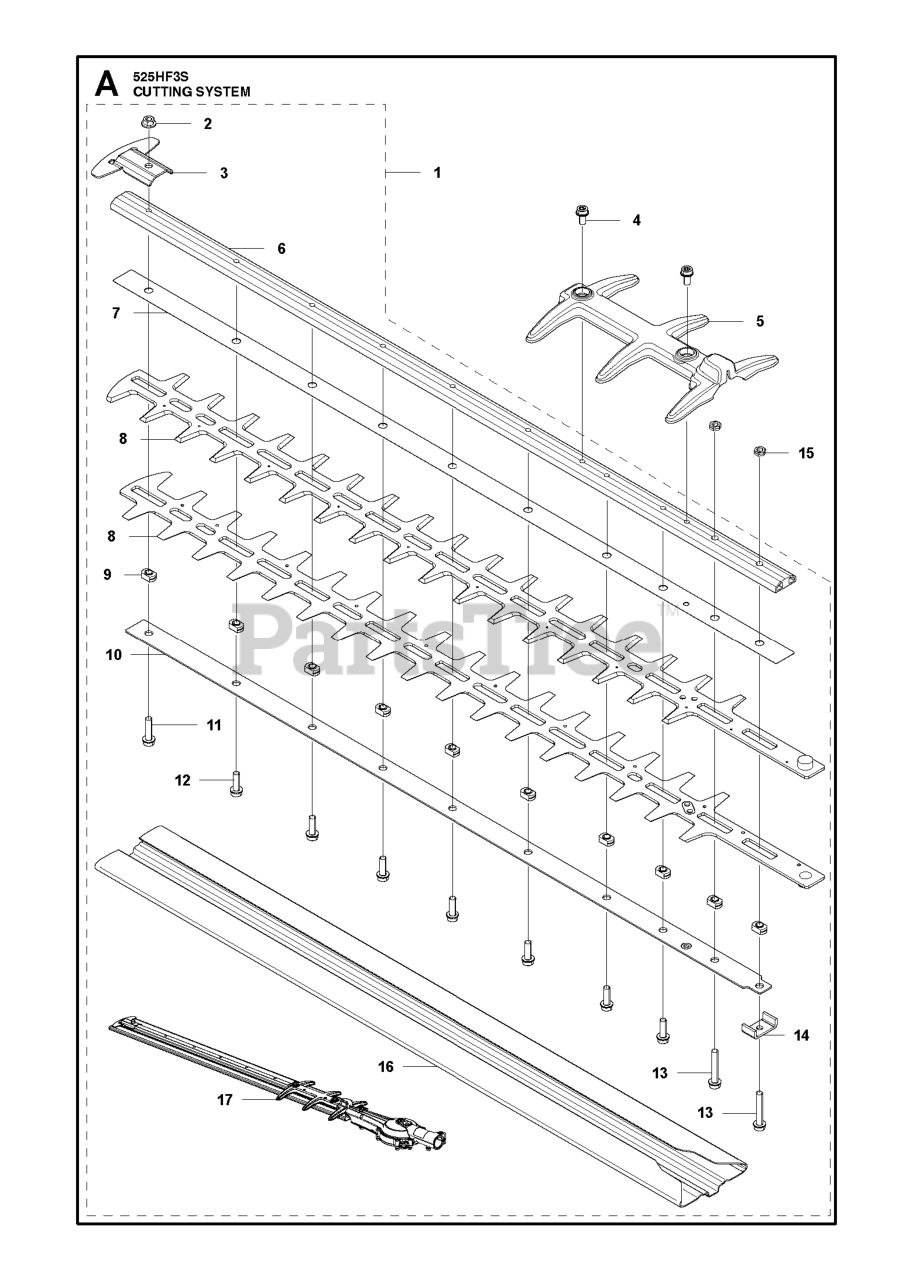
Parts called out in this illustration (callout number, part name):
1	LABEL
3	DECAL.HOOD.NAMELOGO.HUSQ
6	Decal, Fender 100 DB/CE
10	DECAL BTRY SYMBOLS
11	DECAL.INTERNATIONL.CUTFINGER
12	DECAL
17	DECAL PARK BRAKE
20	DECAL.BYPASS.FENDER.CRD.LT.YT
